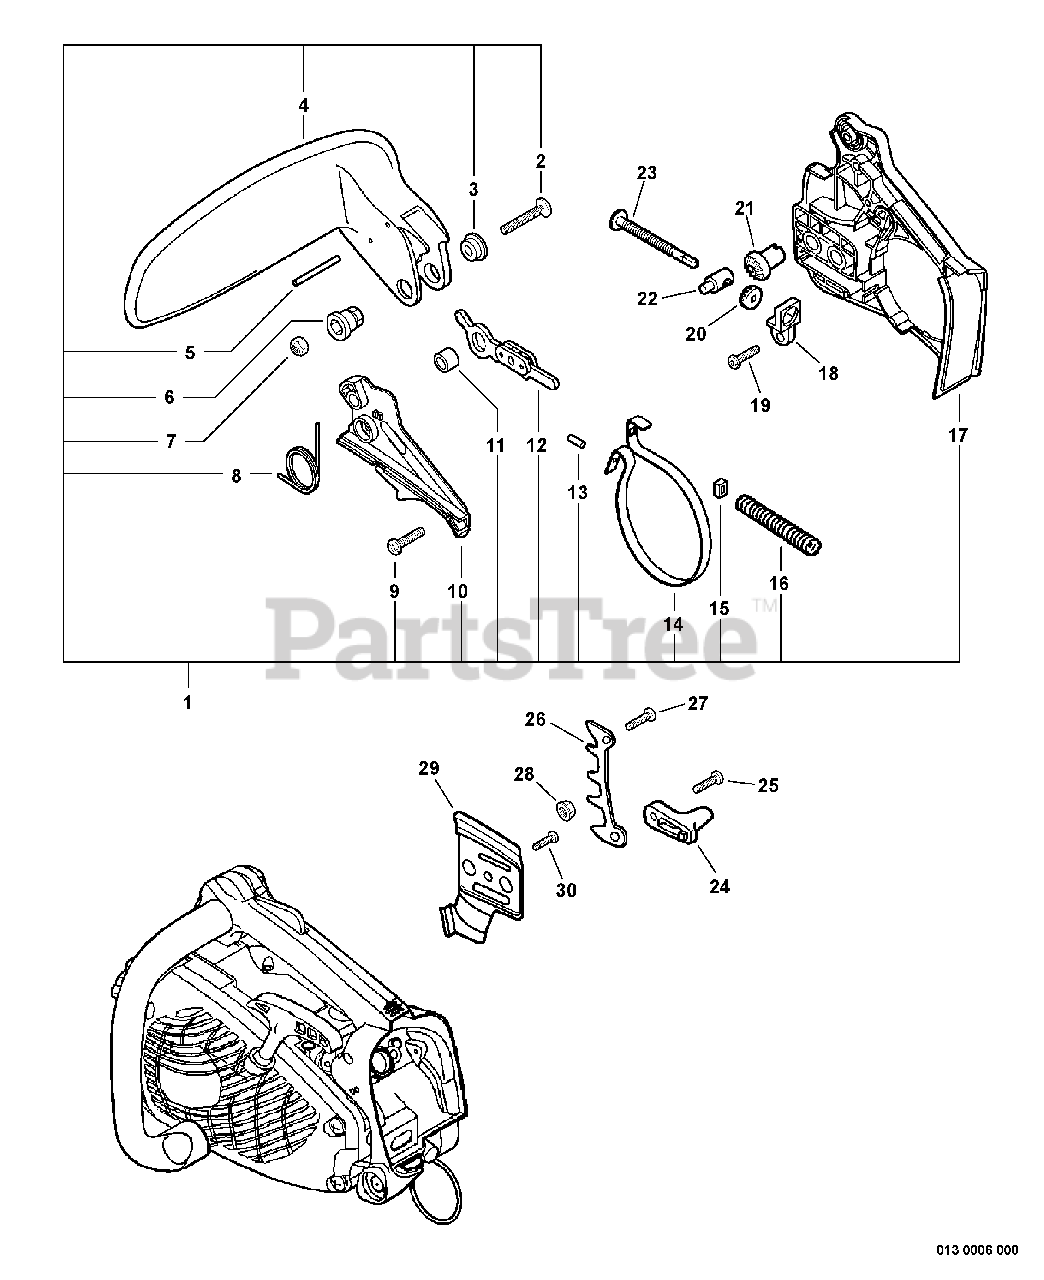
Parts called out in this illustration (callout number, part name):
1	CHAIN BRAKE ASSY - GRAY
2	SCREW - 5X32
4	LEVER, BRAKE - ORANGE
5	PIN - 3X26
6	COLLAR - 5
7	LOCKNUT - 5
9	SCREW - 4X12 -- TAPPING
10	COVER, BRAKE - GRAY
11	SPACER - 8
12	CONNECTOR, BRAKE
13	PIN - SPRING
14	BAND, BRAKE
17	GUARD, SPROCKET - GRAY
18	BRACKET, TENSIONER
19	SCREW - 4X12 -- TAPPING
20	GEAR - BEVEL
21	GEAR - PINION
22	TENSIONER, CHAIN
23	SCREW, TENSIONER
24	CATCHER, CHAIN
25	SCREW - 5X20 -- TAPPING
27	SCREW - 5X20 -- TAPPING
28	NUT - 6 -- FLANGE
29	PLATE, GUIDE - INNER
30	SCREW - 4X10
